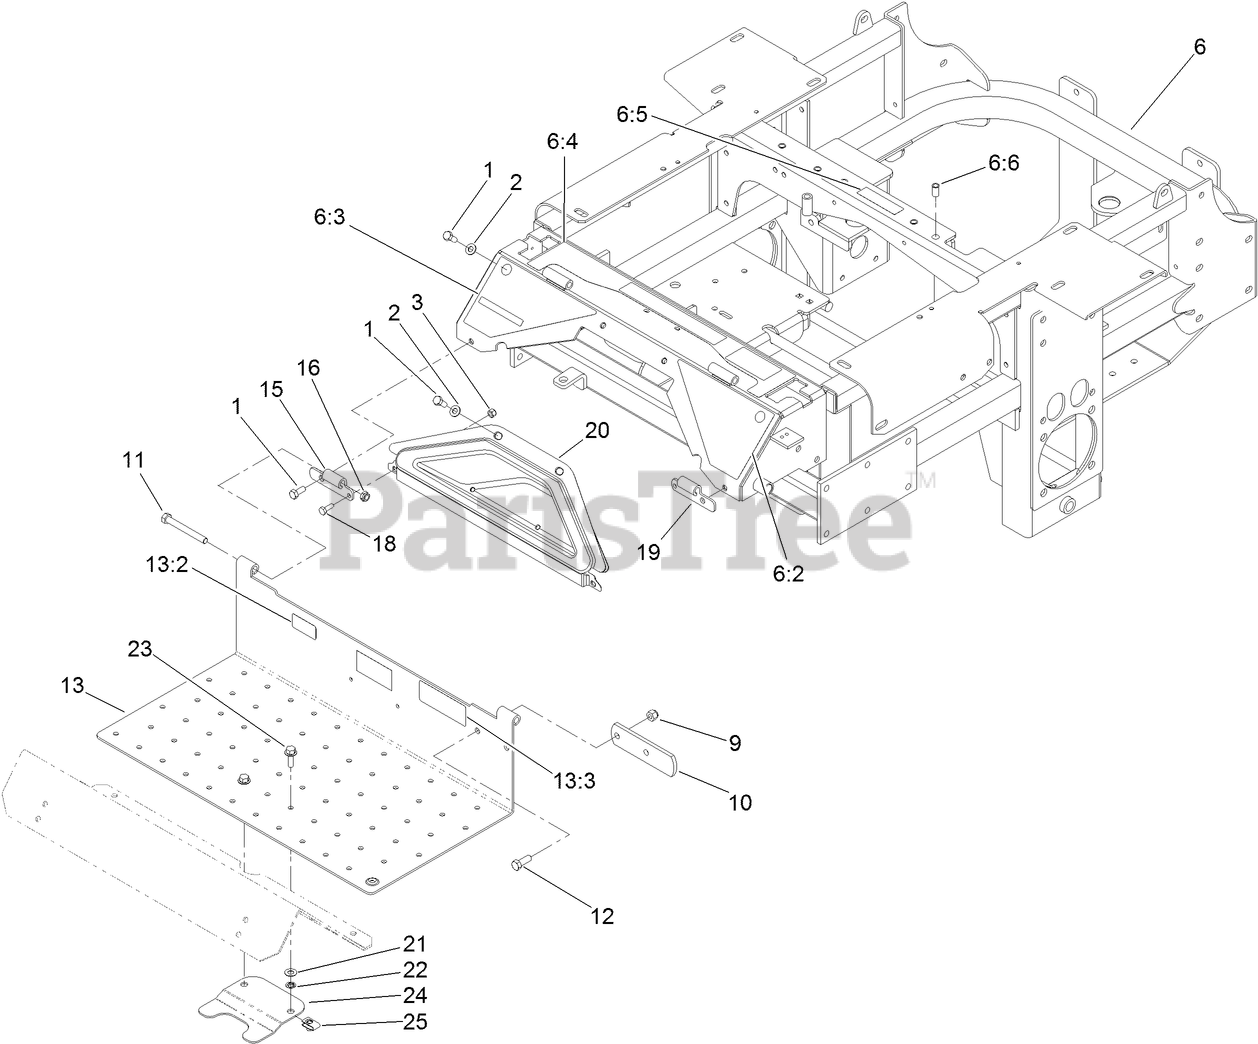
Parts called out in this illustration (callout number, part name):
1	SCREW-HH
2	WASHER-FLAT
3	NUT-LOCK, NI
6:2	DECAL-DANGER, LEFT
6:3	DECAL-WARNING, RIGHT
6:4	DECAL-CONSOLE, TOP (CE)
6:5	DECAL-WARNING
6:6	NUT-CLINCH
9	NUT-LOCK, NI
10	STOP-BRAKE, PARK
11	SCREW-HH
12	SCREW-HH
13	FLOOR PAN ASM
13:2	DECAL-PROTECTION, EAR
13:3	DECAL-DIESEL, BIO-READY
15	HINGE-FLOORPAN, LH
18	SCREW-HH
19	HINGE-FLOORPAN, RH
20	POCKET
21	WASHER-THRUST
22	NUT-PUSH
23	SCREW-HHF
24	ADAPTER-CAPTIVE
25	NUT-U
